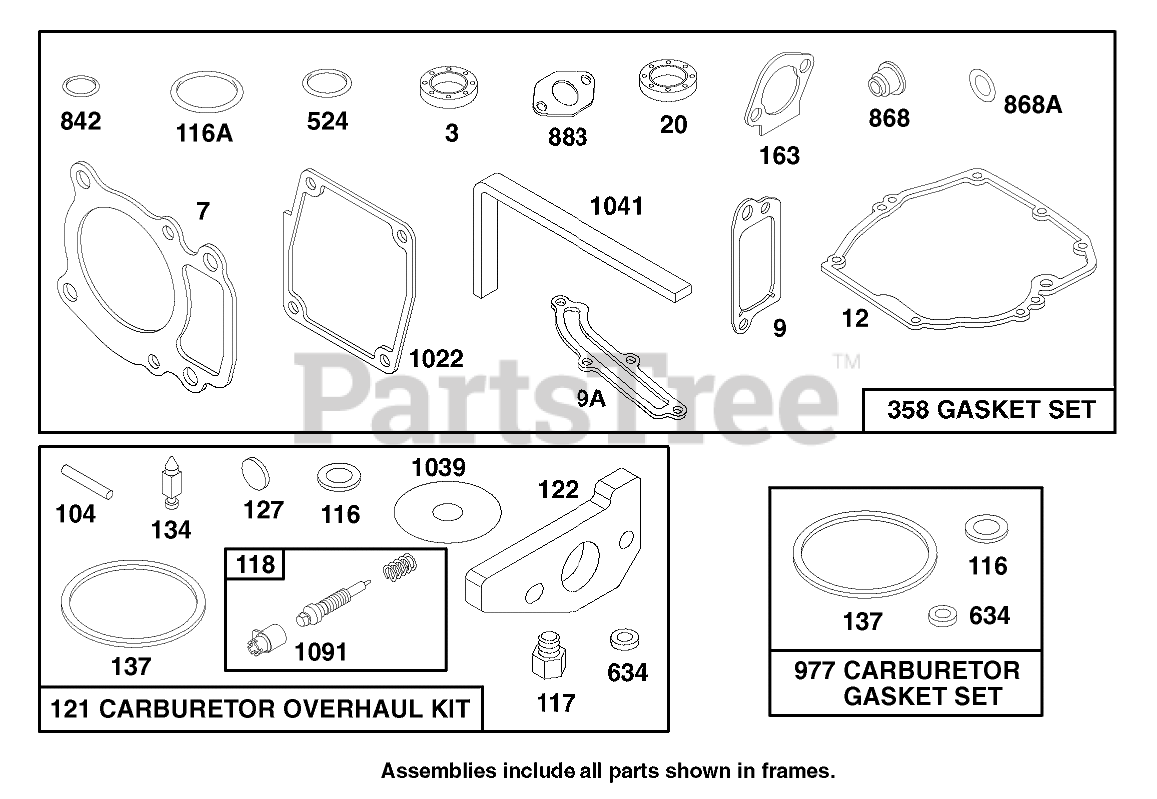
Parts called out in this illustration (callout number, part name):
1	CYLINDER ASSEMBLY
3	SEAL - OIL
7	CYLINDER HEAD GASKET
9	BREATHER GASKET
9A	GASKET-BREATHER
12	ENGINE BASE GASKET
20	SEAL-OIL
104	FLOAT HINGE PIN
116	SEALING GASKET
116A	O RING SEAL
117	Jet-Main
118	VALVE/SPRING - NEEDLE
121	KIT-CARBURETOR OVERHAUL
122	ADAPTER ASSEMBLY
127	PLUG - WELCH
134	Valve-Inlet (Includes Seat)
137	FLOAT BOWL GASKET
163	AIR CLEANER GASKET
188	SCREW - SEM
358	GASKET SET
524	O-RING
634	SEAL WASHER
842	O-RING
868	SealAssy-Valve
868A	Seal-Valve
883	EXHAUST GASKET
977	CARBURATOR GASKET SET
1022	ROCKER COVER GASKET
1039	FLOAT LIMITER
1041	SEAL - FOAM
1091	CAP - LIMITER
